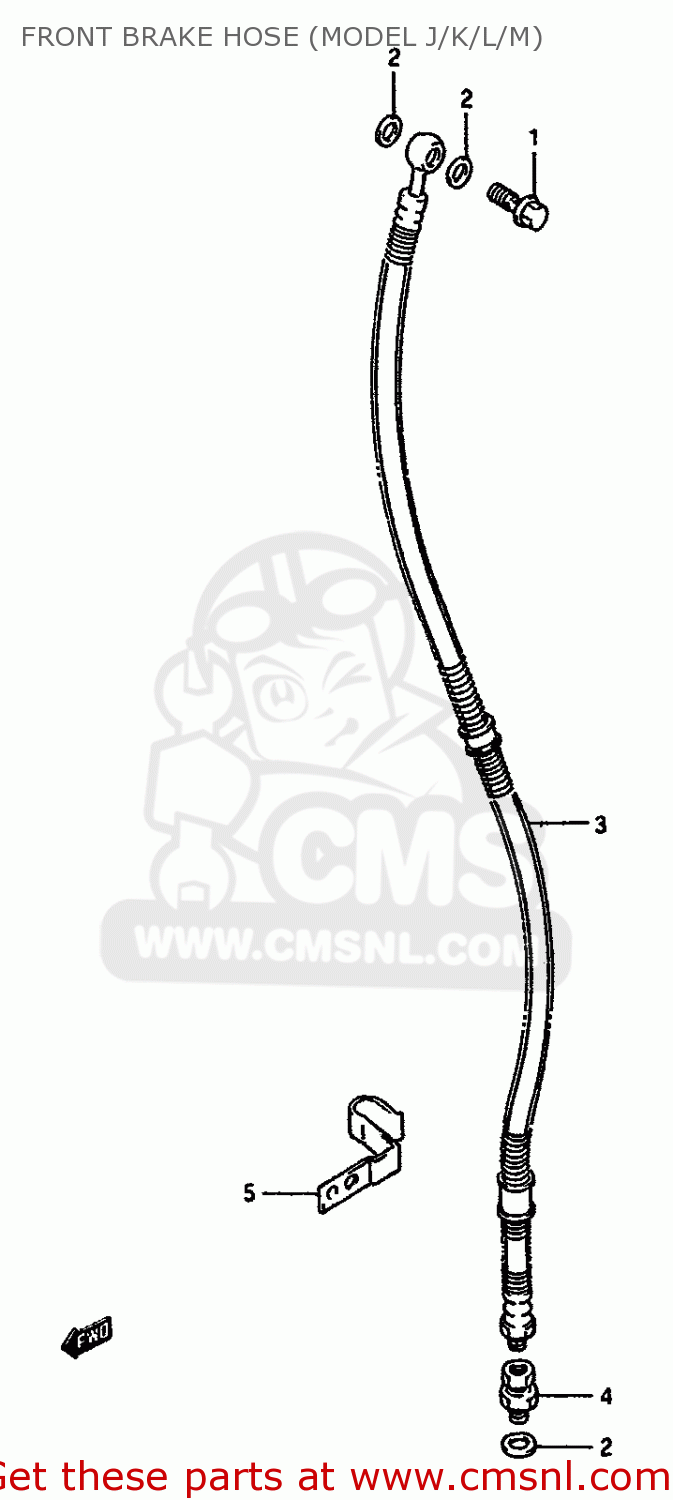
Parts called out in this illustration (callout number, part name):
1	BOLT UNION
2	WASHER(10X15X1.5)
3	HOSE,FR BRAKE
4	ADAPTER,BRAKE HOSE
5	GUIDE,BRAKE HOSE NO.1
6	BOLT
7	GUIDE,BRAKE HOSE NO.2
